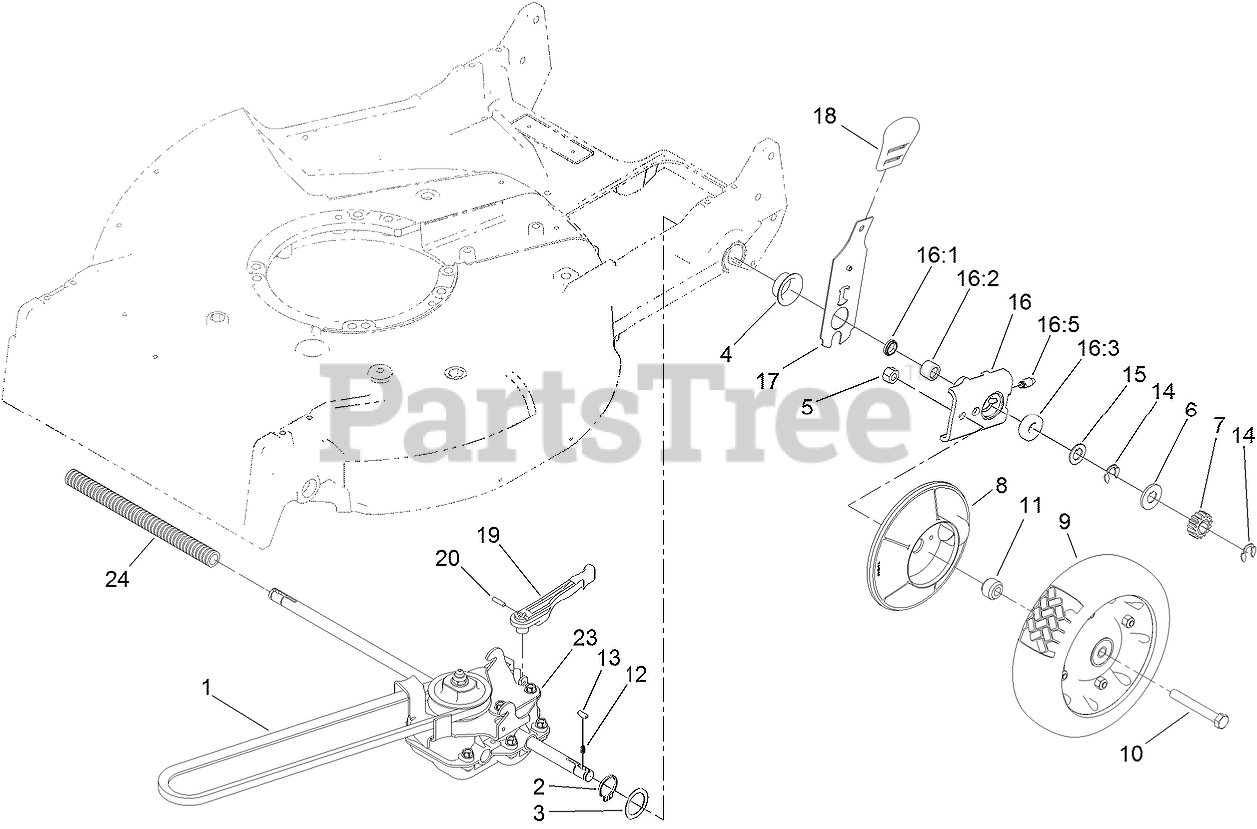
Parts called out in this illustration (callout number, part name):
1	V-BELT
2	RING-RETAINING
3	WASHER
4	CAP-END
5	NUT-LOCK, CONE
6	WASHER-THRUST, OUTER
7	GEAR-PINION
8	COVER-WHEEL
9	WHEEL AND TIRE ASM
10	SCREW-HH
11	SPACER-COVER, WHEEL
12	SPRING-COMPRESSION
14	RING-RETAINING
15	WASHER-THRUST, OUTER
16	PIVOT ARM ASM
16:1	SEAL-OIL
16:2	BEARING-CAGED NEEDLE ROLLER
16:3	BEARING-WHEEL
17	REAR SPRING ARM ASM
18	KNOB-HOC
19	LEVER-SHIFT
20	PIN-COIL
23	GEAR CASE ASM
24	COVER-SHAFT, DRIVE
